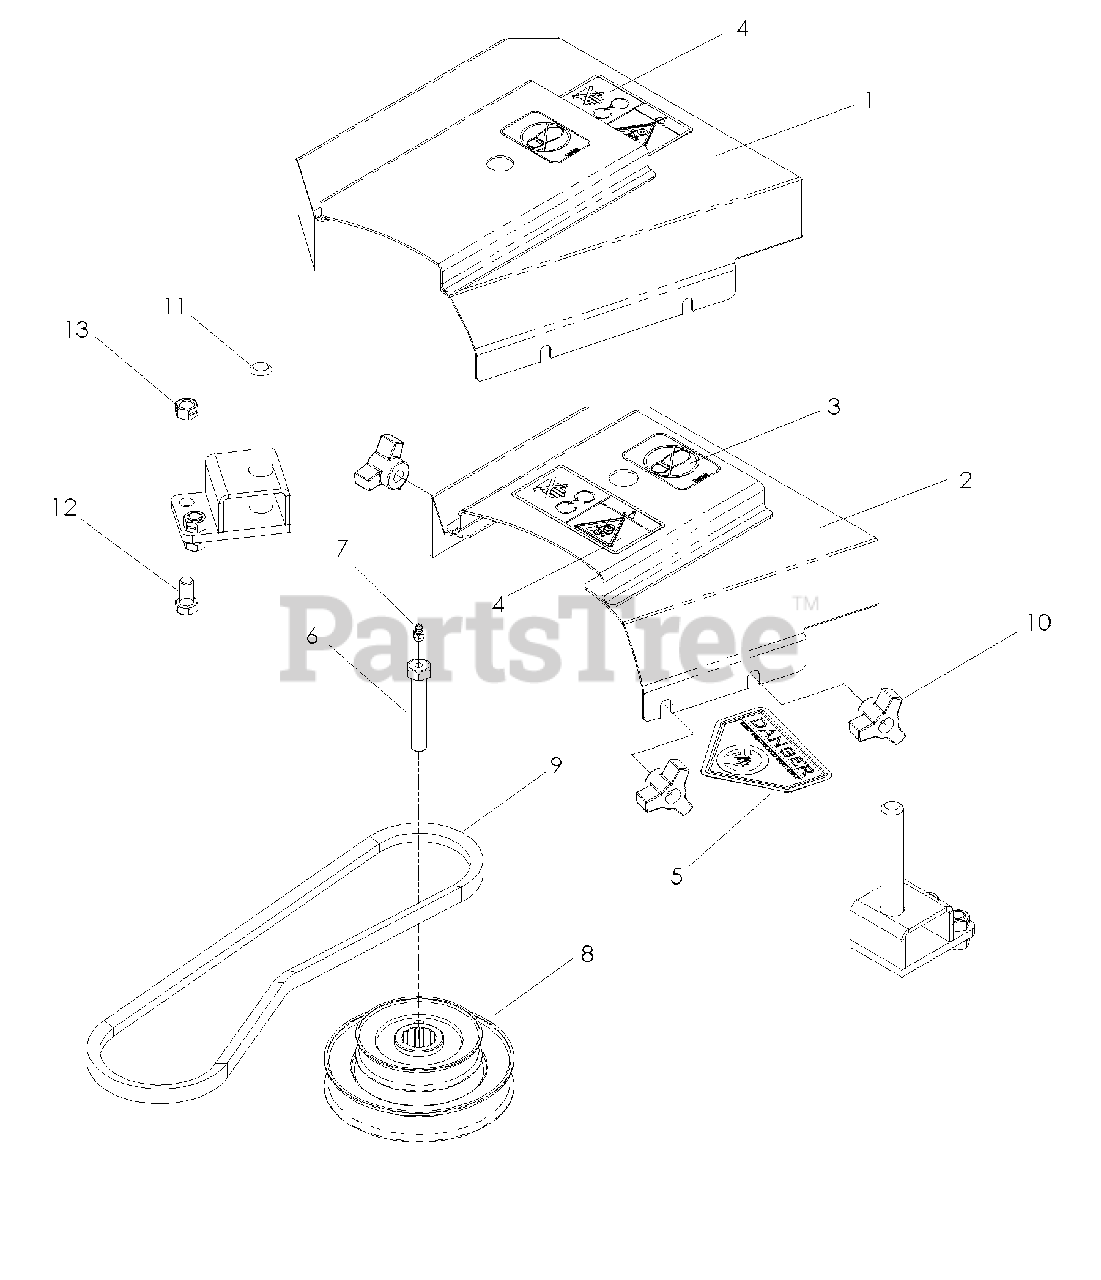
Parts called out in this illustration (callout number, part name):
1	SHIELD W/DECALS 52"
2	SHIELD W/DECALS 61"
3	DECAL, NO STEP
4	DECAL, DANGER BELT DR
5	DECAL, CPSC
6	HCS 7/16-20 x 2 1/2 SPECIAL
7	ZERK
8	PULLEY, DBL, STACKED, 52"
8	PULLEY, DBL, STACKED, 61"
10	KNOB, THREE PRONG
11	BLOWER PIN, SM
12	HCS 3/8-16 x 3/4
13	NUT 3/8 -16 CENTERLOCK
